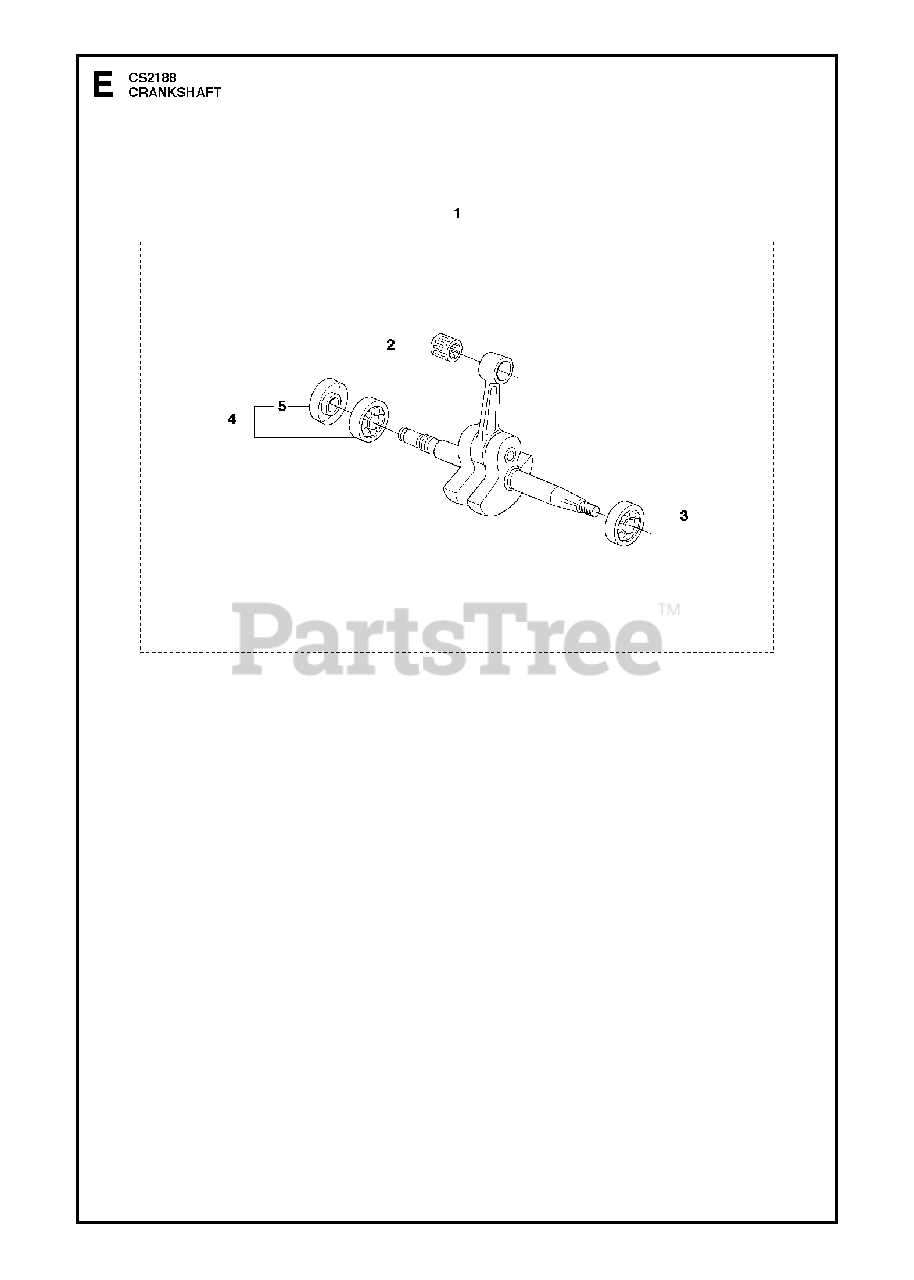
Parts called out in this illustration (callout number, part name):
1	CRANKSHAFT
2	SUPPORT BUSHING
3	BALL BEARING 6203 C3
4	BALL BEARING
5	SEALING RING
